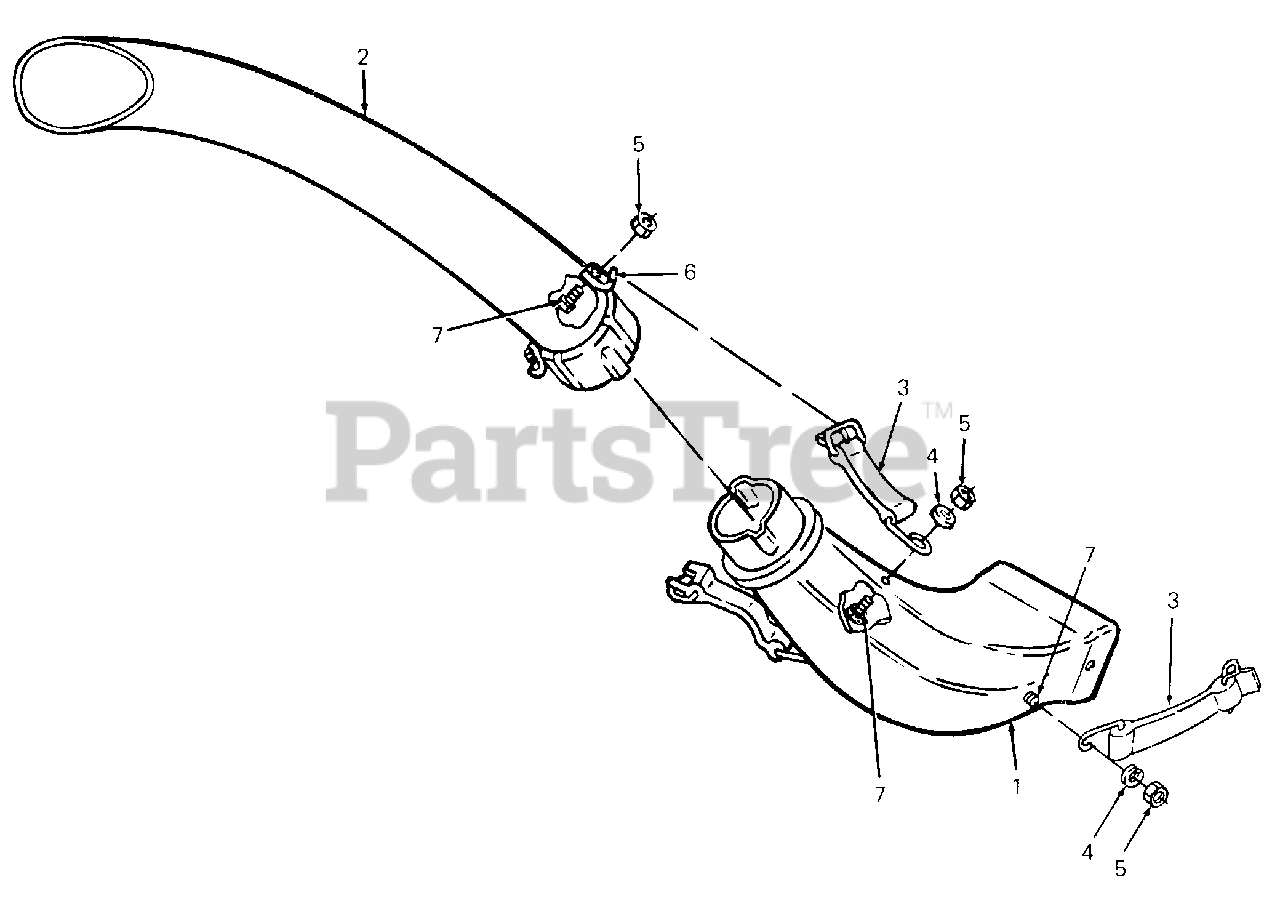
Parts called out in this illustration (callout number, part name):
1	Chute, Discharge
2	Tube, Catcher
3	Strap Ass'y, Retainer
4	Washer, Spring, .265 X .562
5	Nut, Hex Insert Lock, 1/4-20
6	Hook Bracket, Retainer
7	Screw, Hex Cap, 1/4-20 X .62 Lg
